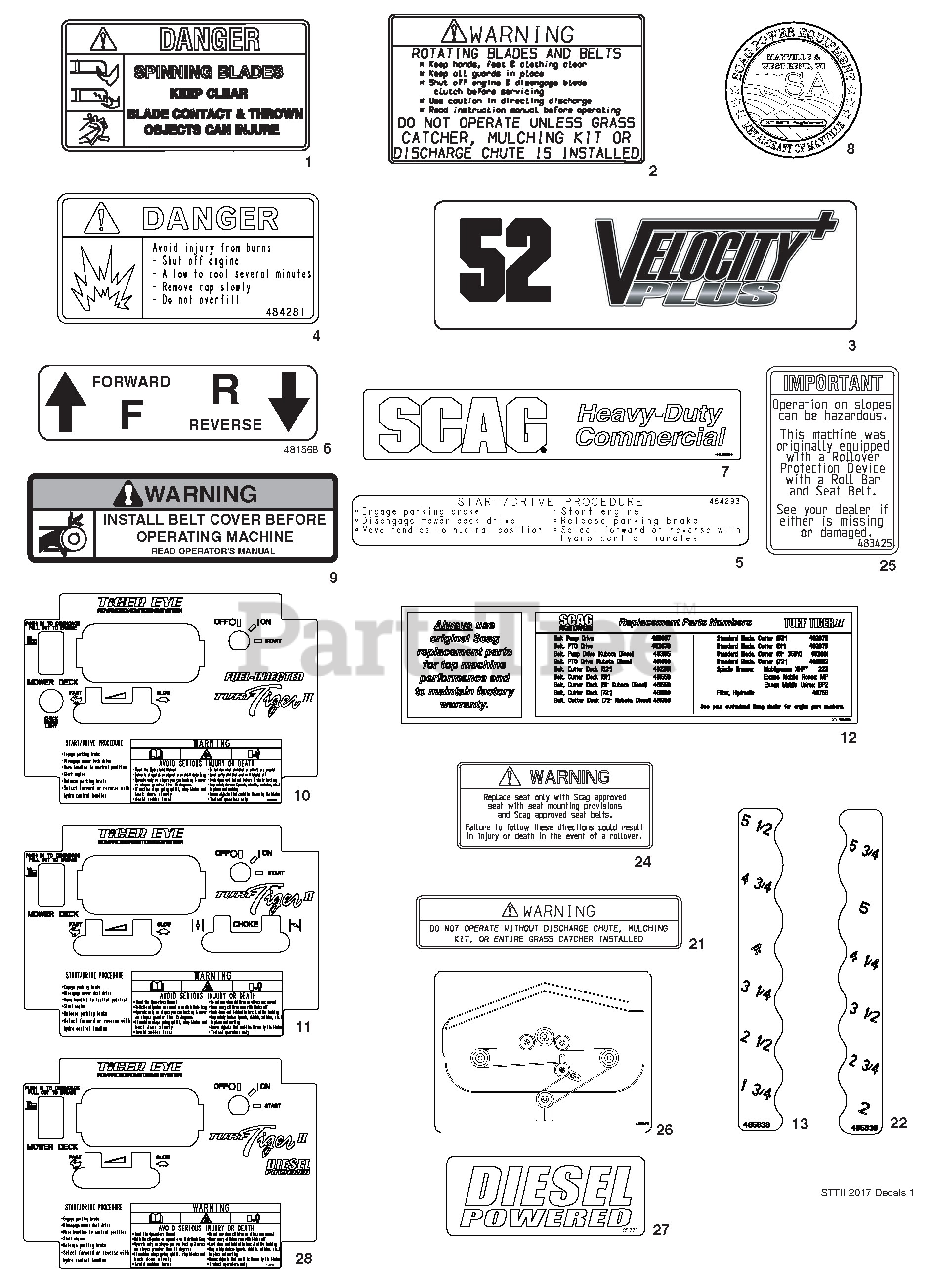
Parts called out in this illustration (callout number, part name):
1	Decal, Danger - Spinning Blades
2	Decal, Warning - Rotating Blades
3	Decal, 52 Velocity Plus
3	Decal, 61 Velocity Plus
3	Decal, 72 Velocity Plus
4	Decal, Fuel Tank - Gasoline Engines
4	Decal, Fuel Tank - Kubota Diesel
5	Decal, Start / Drive
6	Decal, Traction Control
7	Decal, Heavy-Duty Commercial
8	Decal, Metalcraft - USA
9	Decal, Belt Cover
10	Decal, Instrument Panel - Fuel Injected
11	Decal, Instrument Panel
12	Decal, STTII Replacement Parts
13	Decal, Cutting Height - LH
24	Decal, Seat Replacement
25	Decal, ROPS
26	Decal, Belt Routing
27	Decal, Diesel Powered - Kubota Diesel
28	Decal, Instrument Panel - Kubota Diesel
